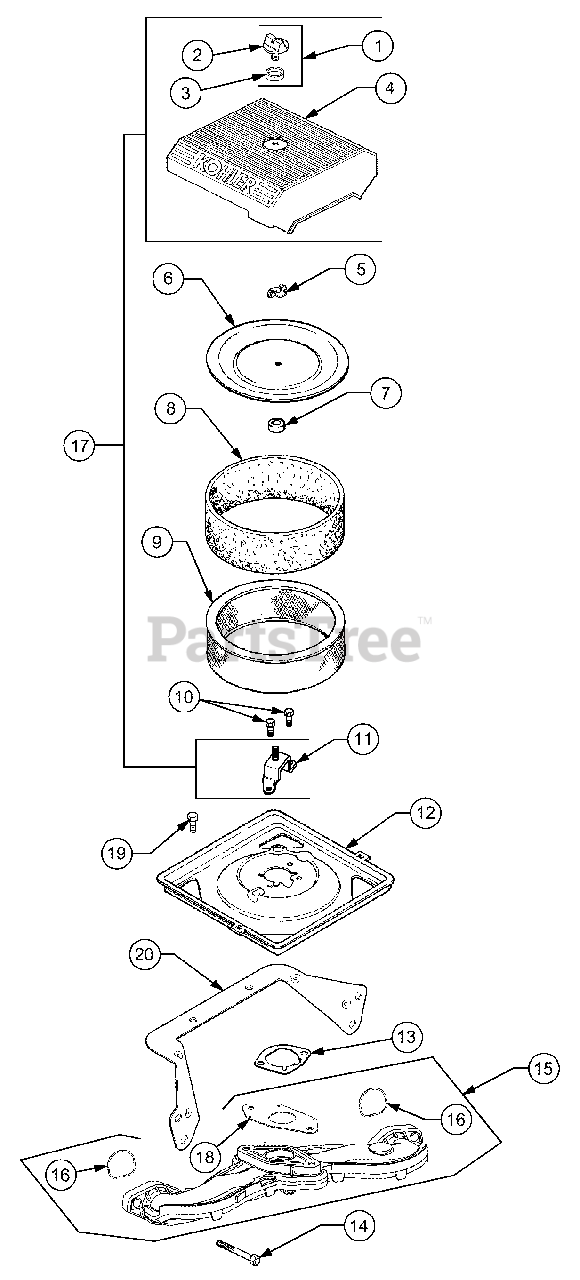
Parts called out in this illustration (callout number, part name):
1	Kit, Knob w/Seal
3	Seal, Air Cleaner Cover Knob
4	Cover, Air Cleaner
6	Cover, Inner Air Cleaner
7	Seal, Inner Air Cleaner
8	Precleaner, Element
9	Element, Air Cleaner
10	Screw, Hex Flange, M6 x 1.0 x 16
11	Bracket, Air Cleaner Base
12	Base, Air Cleaner
13	Gasket, Air Cleaner Base
14	Screw, Hex Flange, M6 x 1.0 x 40
15	Manifold, Intake
16	O-Ring, Intake Manifold
17	Kit, Air Cleaner Cover
18	Gasket, Carburetor
19	Screw, Hex Flng, M5 x 0.8 x 10
20	Bracket, Air Cleaner Base
